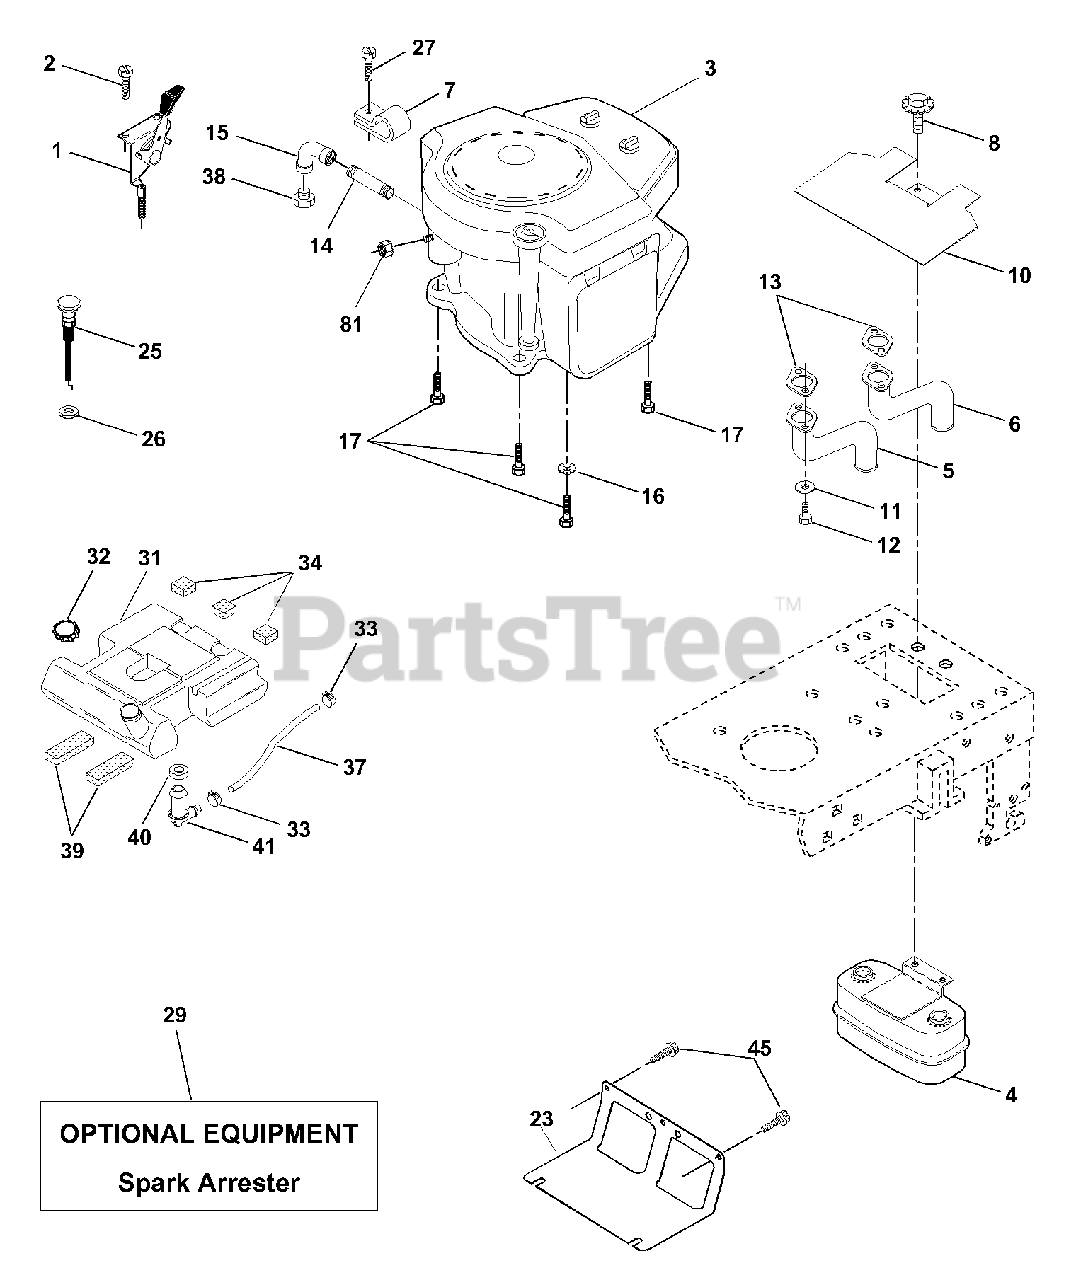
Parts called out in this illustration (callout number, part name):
1	Control Th/ch LH Flag 35.5
2	Screw Hex Thd Cut 1/4-20x5/8 T
4	Muffler Exhaust
5	Exhaust Asm. Left
6	Exhaust Asm Right
7	Clamp Tube Double Engine
8	Bolt 5/16-18 UNC x 3/4 W/Sems
10	Heat Shield LT
11	Washer Lock Hvy. Helical 1/4
12	Bolt Fin Hex 1/4-20 x 3/4
13	Gasket Muffler
14	Nipple Pipe 3/8 Npt X 3"
15	Elbow Std 90 Degree 3/8-18 Npt
16	Washer Lock Ext Tooth 3/8
17	Screw Thdrol 3/8-16 x 1-1/2 Tytt
23	Shield Browning/Debris Guard
25	Control Choke
26	Nut Keps 3/8-24 UNF
27	Screw TT Flange
29	Kit Spark Arrestor (Flat Scrn)
31	Tank Fuel Front
32	Cap Asm Fuel
33	Clamp Hose
34	Strip Foam
37	Line Fuel
38	Oil Drain Plug
39	Pad Spacer
40	Bushing
41	Stem Tank Fuel
45	Screw Hex Wsh Thdrol 3/8-16 x 3/4
81	Nut Keps Hex 1/4-20 Unc
